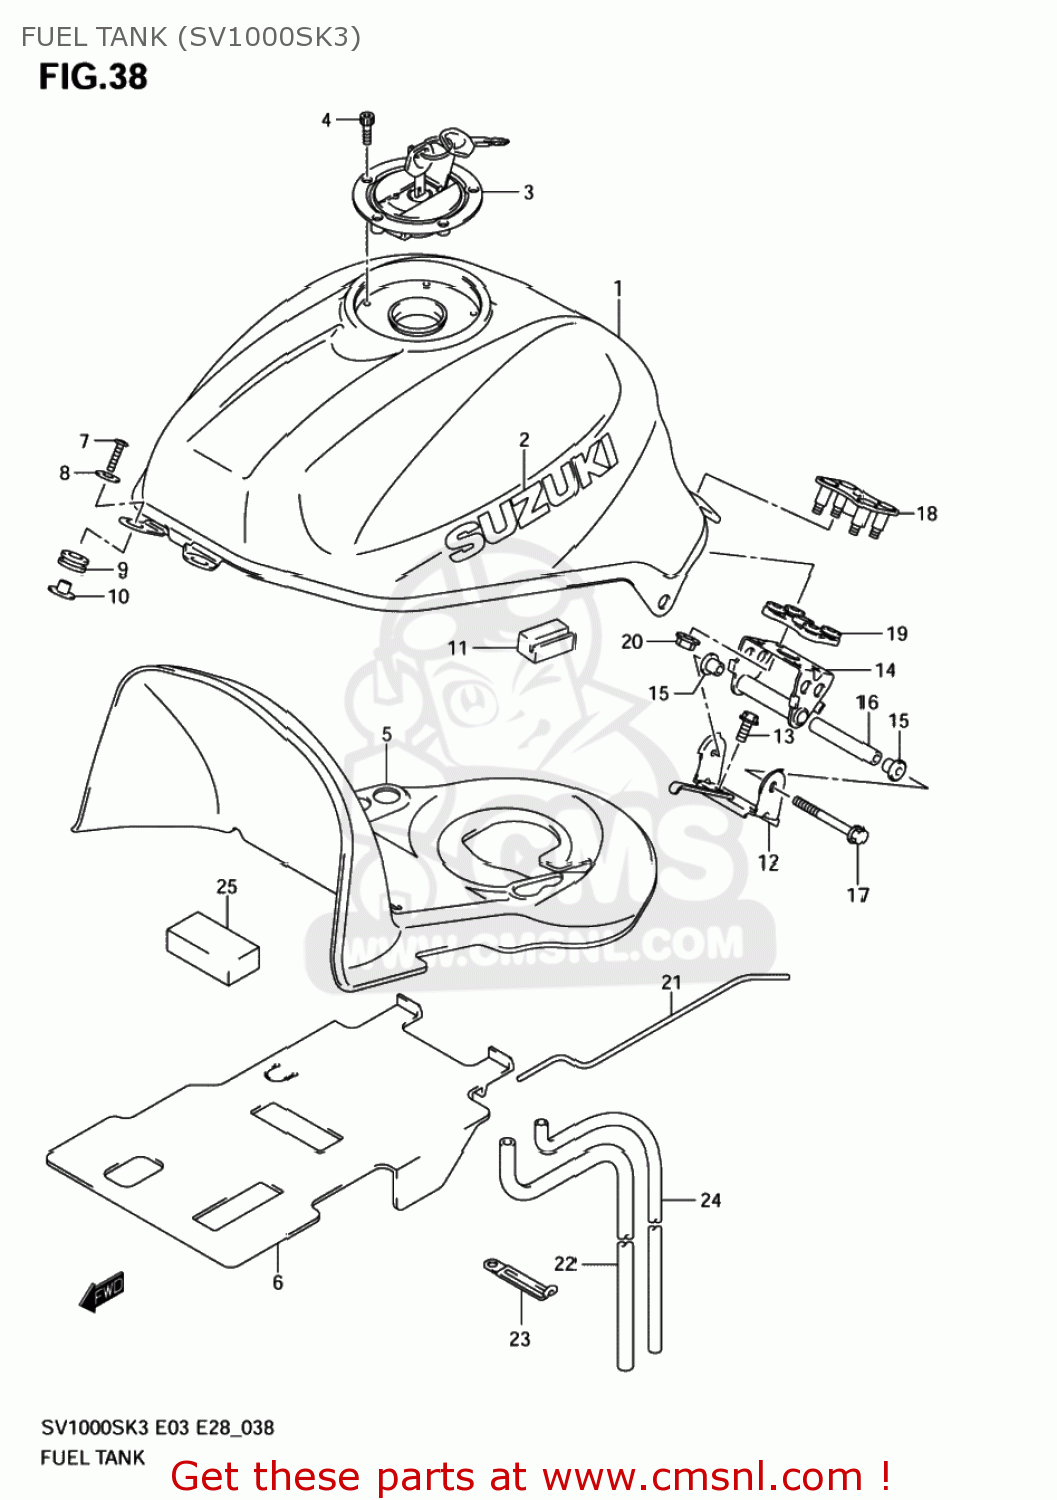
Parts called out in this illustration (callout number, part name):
1	TANK ASSY,FUEL(SILVER)
2	EMBLEM
3	CAP SET,FUEL TANK
4	BOLT(5X20)
5	SHIELD,FUEL TANK HEAT
6	SHEET,HEAT SHIELD RUBBER
7	SCREW(6X25)
8	WASHER(6.5X22X1.6)
9	CUSHION,FUEL TANK FR
10	SPACER,FUEL TANK FR
11	CUSHION,FUEL TANK SIDE
12	BRACKET,FUEL T
13	BOLT
14	BRACKET,FUEL TANK NO.1
15	CUSHION,TANK RR BRACKET
16	SPACER,FUEL TANK RR
17	BOLT(6X100)
18	BRACKET,FUEL TANK RR UP
19	CUSHION,FUEL TANK RR
20	NUT
21	STAY,FUEL TANK
22	HOSE,WATER DRAIN
23	CLAMP(L:80)
24	HOSE,FUEL TANK
25	CUSHION,FUEL TANK
